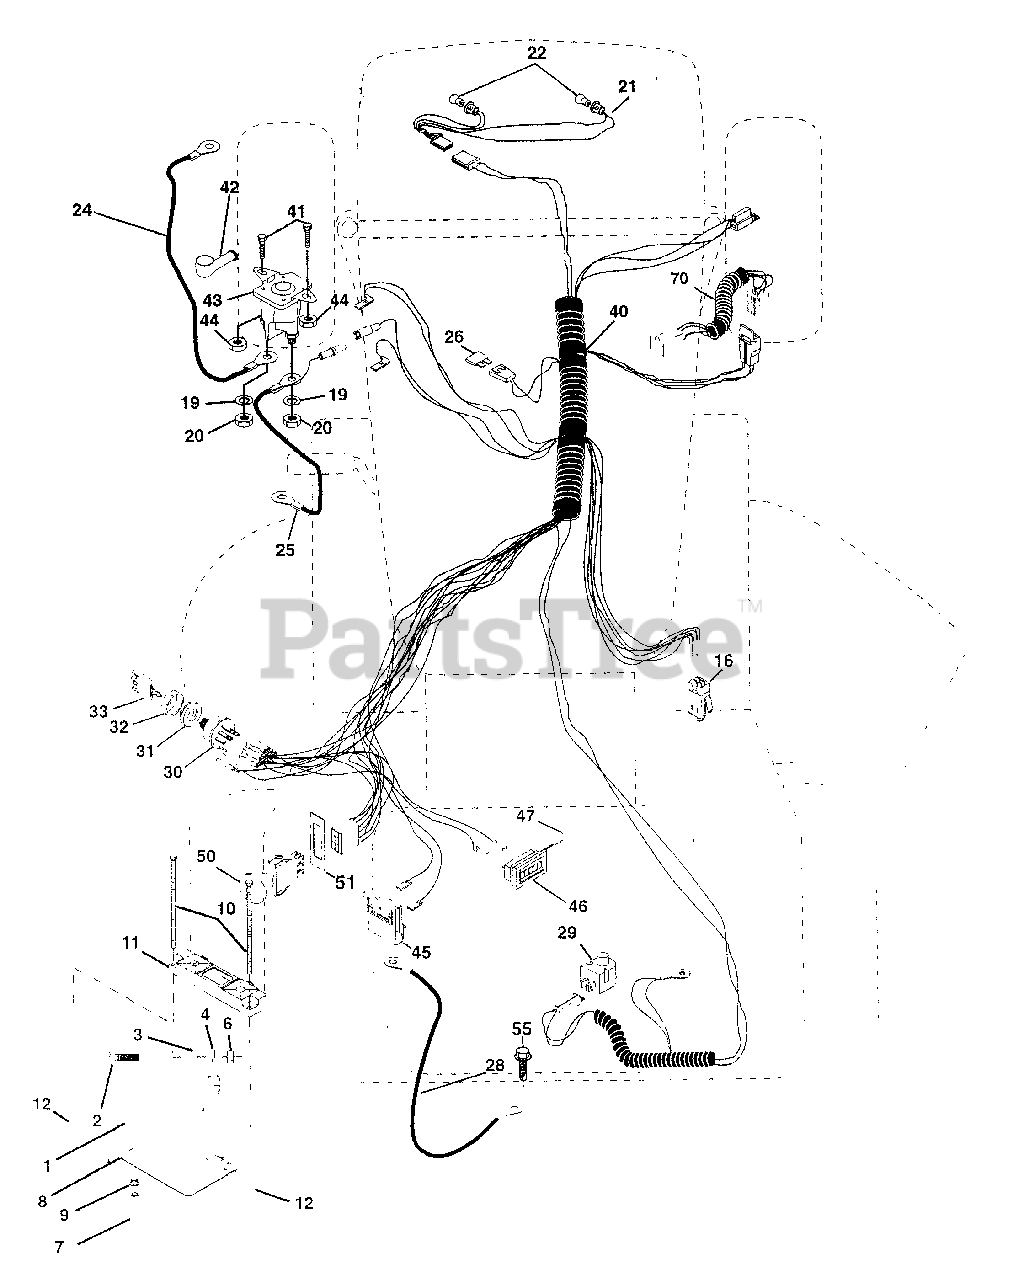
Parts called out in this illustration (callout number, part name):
1	Battery 12 Volt 35 AMP
2	Bolt Hex Hd 1/4-20unc X 3/4
3	Washer 9/32 X 5/8 X 16 Ga.
4	Washer Lock Hvy Helical 1/4
6	Nut Fin Hex 1/4-20 Unc
7	Tube Plastic 46" Front Battery
8	Case Battery Mech Hinge
9	Clamp Hose Olive
10	Bolt Brt Frt 1/4-20 x 75 Ainc
11	Holddown Battery Front Mount
12	Nut Push Nylon 1/4" Battery Frt
16	Switch Interlock Push-In
19	Washer Lock 1/4
20	Nut Jam Hex 1/4-20 Unc
21	Harness Asm Light W/4152j
22	Bulb Light #1156
24	Cable Battery 6 Ga 11" red
25	Cable Battery 6 Ga 22" red w/16 wire
26	Fuse 30 AMP Auto Green
28	Cable Ground 6 Ga 21" black
29	Switch Plunger Nc Gray
30	Switch Ign 4 pos w/lights
31	Nut Ignition
32	Cover Sw Ignition
33	Key Ign Modelled Generic
40	Harness Ign.
41	Bolt Blk Fin Hex 1/4 - 20 x 1/2
42	Cover Terminal Red
43	Solenoid
44	Nut Keps Hex 1/4-20 Unc
45	Ammeter Rectangular 15 Amp
46	Meter Hour
47	Screw 10-24 x 1/2 Black
50	Switch PTO 3 PDT Black Delta 96
51	Ring Retainer PTO
55	Screw Thdrol 5/16-18 x 1-1/2 Tyt
70	Harness, Eng.
